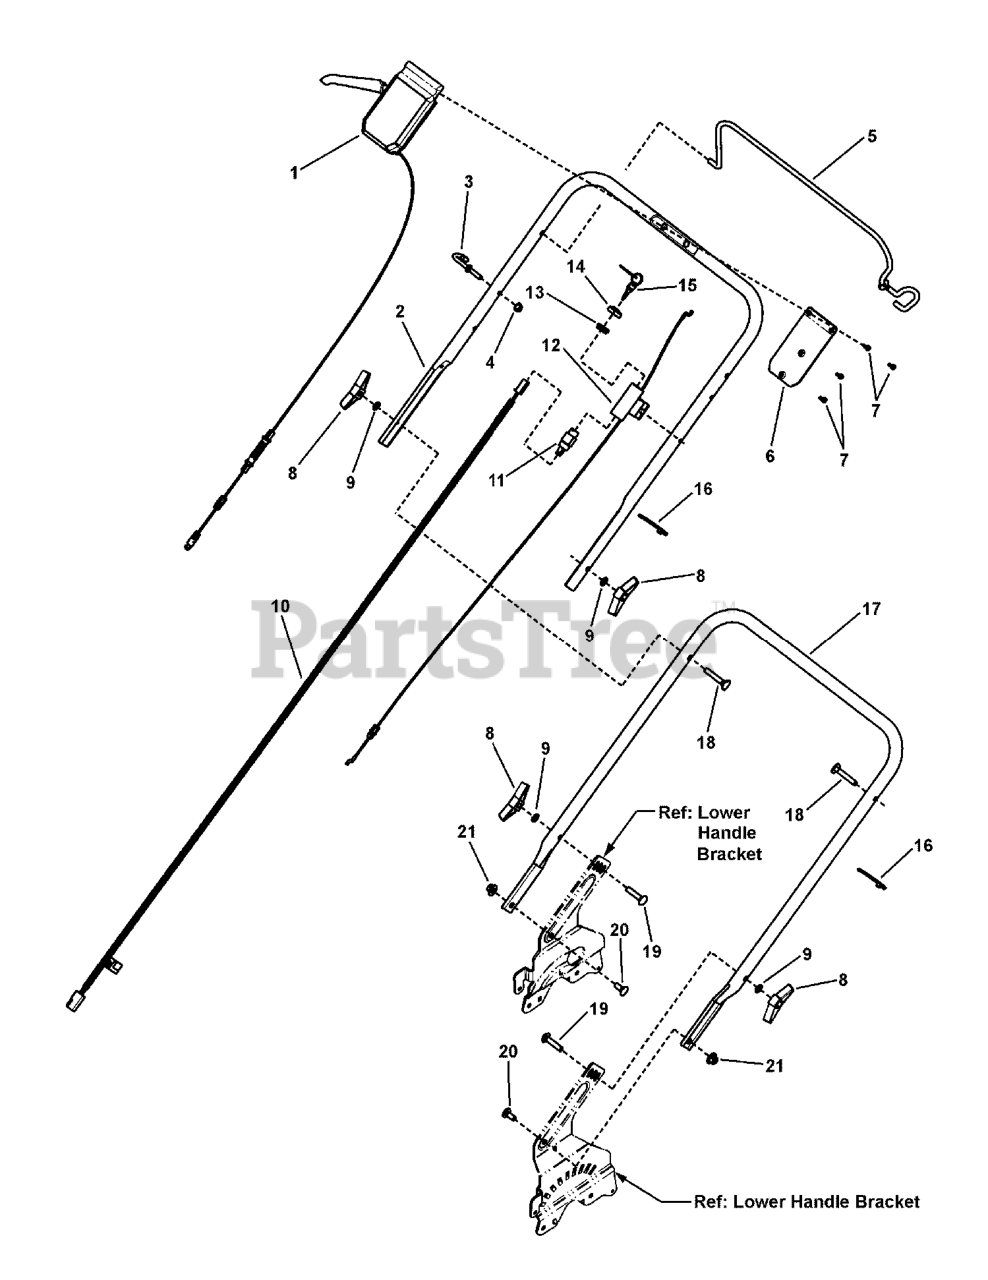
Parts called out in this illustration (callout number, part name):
1	ASSY, Control Box, VS, RWD
2	HANDLE, Upper, Brute, Propelled
3	GUIDE, Rope (1/4-20 thread)
4	NUT, 1/4-20 Hex Flange Lock (Esna)
5	BAIL, Brute SP, Operator Presence Control
6	PLATE, Control Panel
7	SCREW, #8-16 Recessed Pan Head (Torxplus)
8	KNOB, 5/16-18 Wing Nut
9	WASHER, 5/16" Internal Tooth Lock
10	WIRING HARNESS, El Start, WBM
11	IGNITION SWITCH, E/S (Start/Run)
12	CABLE, Bail, 21", WBM, Brute, E/S
13	NUT, 5/8-32, E-Start
14	CAP, E-Start
15	IGNITION KEY (Pair)
16	WIRE TIE,11 Inch Std Blk Nylon
17	HANDLE, Lower 21" RD
18	BOLT, 5/16-18 x 2" Curved Head Square Neck
19	BOLT, 5/16-18 x 1-1/2" Round Head Short Square Neck, GR 5
20	BOLT, 5/16-18 x 3/4" Round Head Short Square Neck, GR 5
21	NUT, 5/16-18 Hex Large Flange Center Lock
